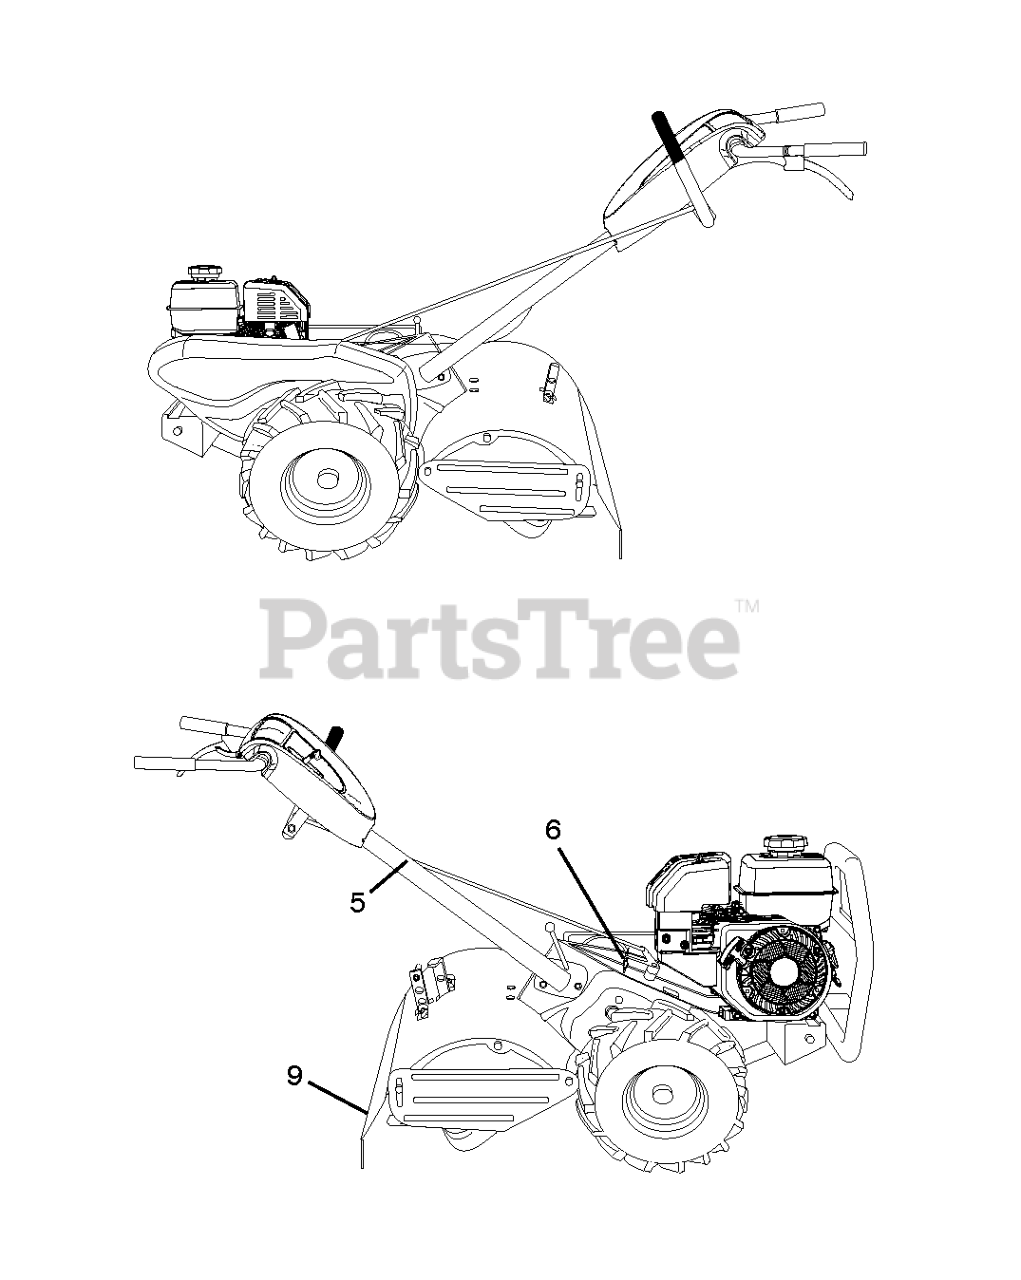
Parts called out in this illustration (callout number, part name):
5	DECAL.PLACEMENT.HAND.SYMBOLS
6	DECAL.SHIFT.INDICATOR.TILLER
9	DECAL.WARNING.4-SYM.TILLER.INT
